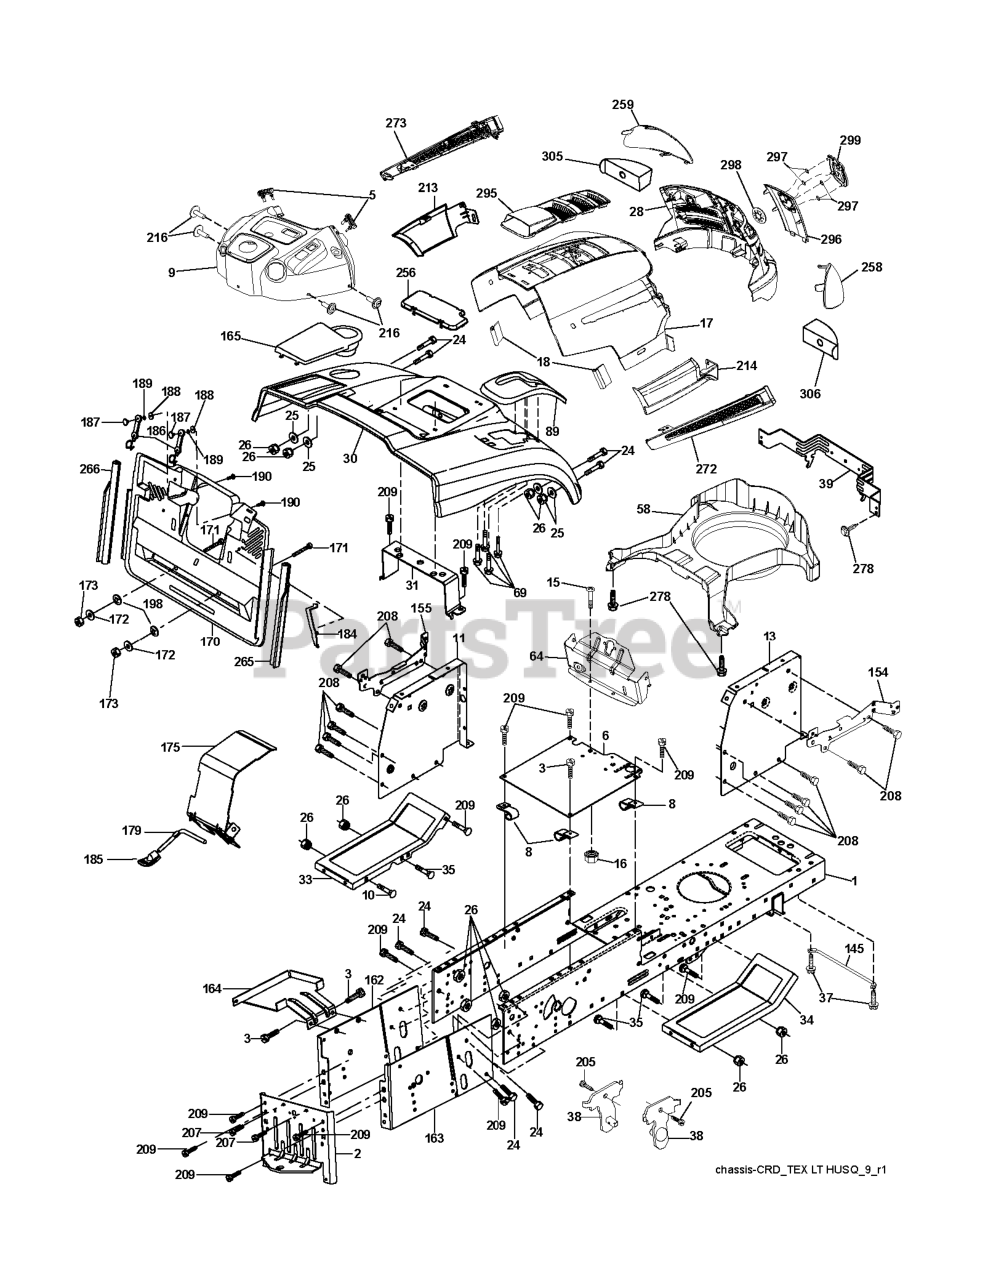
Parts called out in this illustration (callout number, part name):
2	DRAWBAR
3	SCREW 3/8-16X3/4
5	BUMPER DASH
6	PLATE
8	CLIP,INSULATOR
10	BOLT D
11	PANEL.DASH.LH.LTX
13	PANEL ASM, DASH RH
15	Screw, Machine, Truss Head 5/16-18 UNC x 3/4
16	NUT
17	HOOD
18	BUMPER.HOOD.TEX.HUSQVARNA
25	WASHER
26	NUT
28	RP GRILLE/LENS ASM.
30	CONSOLE.CRD.AUTO.GRY
31	BRACKET SUPPORT FENDER
33	FOOTREST PNT LH
34	FOOTREST PNT RH
37	Screw 5/16-18 x 1/2 Hex, Self Tapping 5/16-18 x 1/2
38	BRACKET ASM PIVOT MOWER REAR
39	BRACKET PIVOT
69	SCREW.HI-LO.CONSOLE
89	CONSOLE.CRD.AUTO.GREY.2005
145	ROD.PIVOT.HOOD
162	BRACKET
163	BRACKET EXTEN CHASSIS RH CRD
165	RP.COVER.BATTERY.CRD.GREY
172	WASHER
175	DOOR TRAP
179	ROD PIVOT FBI
184	BRACKET.ACTUATOR.BAGGER.SRD
186	LATCH ASSY
187	WELDNUT
189	LOCKWASHER #10
190	SCREW
207	SCREW, 5/16-18 X 1/2
208	SCREW 3/8-16X1/2
209	SCREW, 3/8-16X3/4
213	SKIRT SIDE LH
214	SKIRT SIDE RH
216	SCREW HEXWSHR 1/4-20X3/4
256	COVER FENDER CRD
258	LENS.HUSQVARNA LT.RH
259	LENS.HUSQVARNA LT.LH
265	SEALING
266	SEALING
272	VENT SIDE HOOD RH
273	VENT SIDE HOOD LH
278	SCREW
295	VENT TOP HOOD
296	TRIM
297	CLIP.RETAINER.TINNER.
298	NUT PUSH M
299	RP LOGO
305	INSERT REFLECTIVE
306	INSERT.REFLECTIVE.RH.
